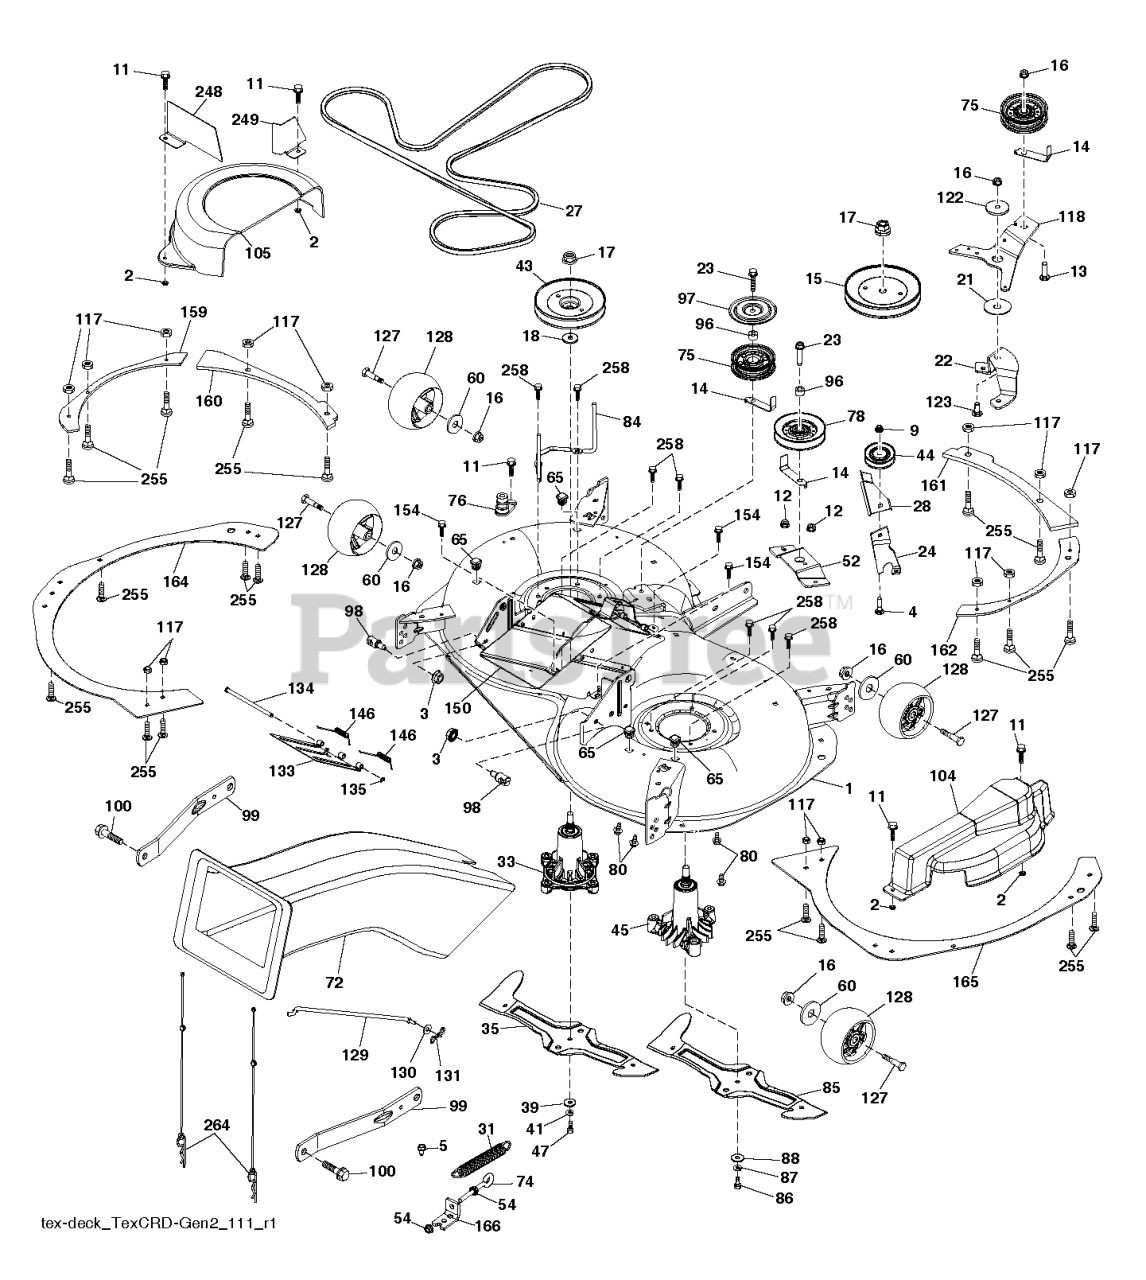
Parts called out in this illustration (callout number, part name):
1	KIT.SVC.DECK.WELD.107HP.EL.498
2	PALNUT 1/4
3	GSPW Nuts
4	BOLT.CARRIAGE.5/16-18
5	BOLT.5/16HEX.WHS.HD
9	NUT HEX FLG NYLOCK BLK 5_16-1
11	SCREW.1/4-20X5/8
12	5/16-18 NYLOC FLANGE NUT
13	GSPW Bolts
14	KEEPER, BELT IDLER
15	PULLEY.MANDREL.5.438.P
16	NUT LOCK FLG 3/8-16 UNC
17	NUT.FLANGE.LOCK.TOP
18	WASHER.SPACER.MANDREL
22	BRACKET CRD IDLER ARM MOUNT BL
23	BOLT;HEX_3/8-16 X 1.78.CLRZINC
24	BRACKET 107 CRD ANGLED V-IDLER
27	BELT 107 CRD DECK DRIVE BELT
28	KEEPER 107 CRD ANGLED IDLER KE
31	SPRING.EXTN.42.FCS.TR.DECK.DRV
33	KIT.MANDREL.NONGREASE.TALL
35	BLADE.3N1.LH.CRD
39	WASHER.7/16.FLAT
43	PULLEY PULLEY MANDREL 5.438 PD
44	PULLEY.V-IDLER.
45	MANDREL ASM.CRD RH 6PT STAR
47	SCREW.SEMS.7/16-20X1.HEX.HEAD
52	BRACKET 107 CRD CENTER V-IDLER
54	GSPW Hardware
72	CHUTE.SLOTTED.HOLES.TEX.CRD.II
74	GSPW Bolts
75	PULLEY.IDLER.FLAT
76	PORT.WASHOUT
78	REPL BY 532 1467-63
80	GSPW Bolts
84	KEEPER KEEPER. LH MANDREL BELT
85	BLADE.3N1.RH.CRD
86	BOLT.3/8-24X1.25GR8. LHTHRD
88	WASHER.BLADE
96	SPACER
97	PROTECTOR
98	STUD.W/"D"ANTI-ROTATION
99	ARM.SUSPENSION.MOWER.R
100	BOLT.SHOULDER
104	COVER.MANDRE.107.CRD.VAC.GUARD
105	COVER.MANDREL.107.LH.GEN.2
117	NUT T
118	ARM 107 CRD CLUTCHING ARM BLAC
122	SPACER.RETAINER.MOWER
128	WHEEL.GAUGE.RALLY
129	ROD ROD. SWAY CRD GEN II
131	PIN.COTTER.5/16.BOW TI
133	COVER DOOR.107 CM CRD EZ MULCH
134	PIN PIN.HINGE
135	E-RING.5/16"
146	SPRING SPRING: EZ MULCH DOOR
150	CHUTE.107TCRD.X-MULCH.CHT.EDIP
154	SCREW T-30 1/4-20 X
159	REINFORCE.PLATE.LH.FT.X431
160	REINFORCE.PLATE.LHS.BOLT.431
161	REINFORCE.PLATE.RH.FRT.X431
162	REINFORCE.PLAT.RH.SD.BLT.X431
164	BAFFLE.PLATE.PNT.107CRD.LT.BLK
165	BAFFLE.PNT.107.CRD.PLATE.RT.BK
166	BRACKET CRD ELEC DECK DRIVE TE
248	GUARD BELT.CRD.LH.REAR.ISO X43
249	GUARD BELT.CRD.LH.FRNT.ISO X43
255	RHSNB, 1/4-20 X 1, GR5
258	BOLT.HEX.WASHR.HED.313-18X1.19
